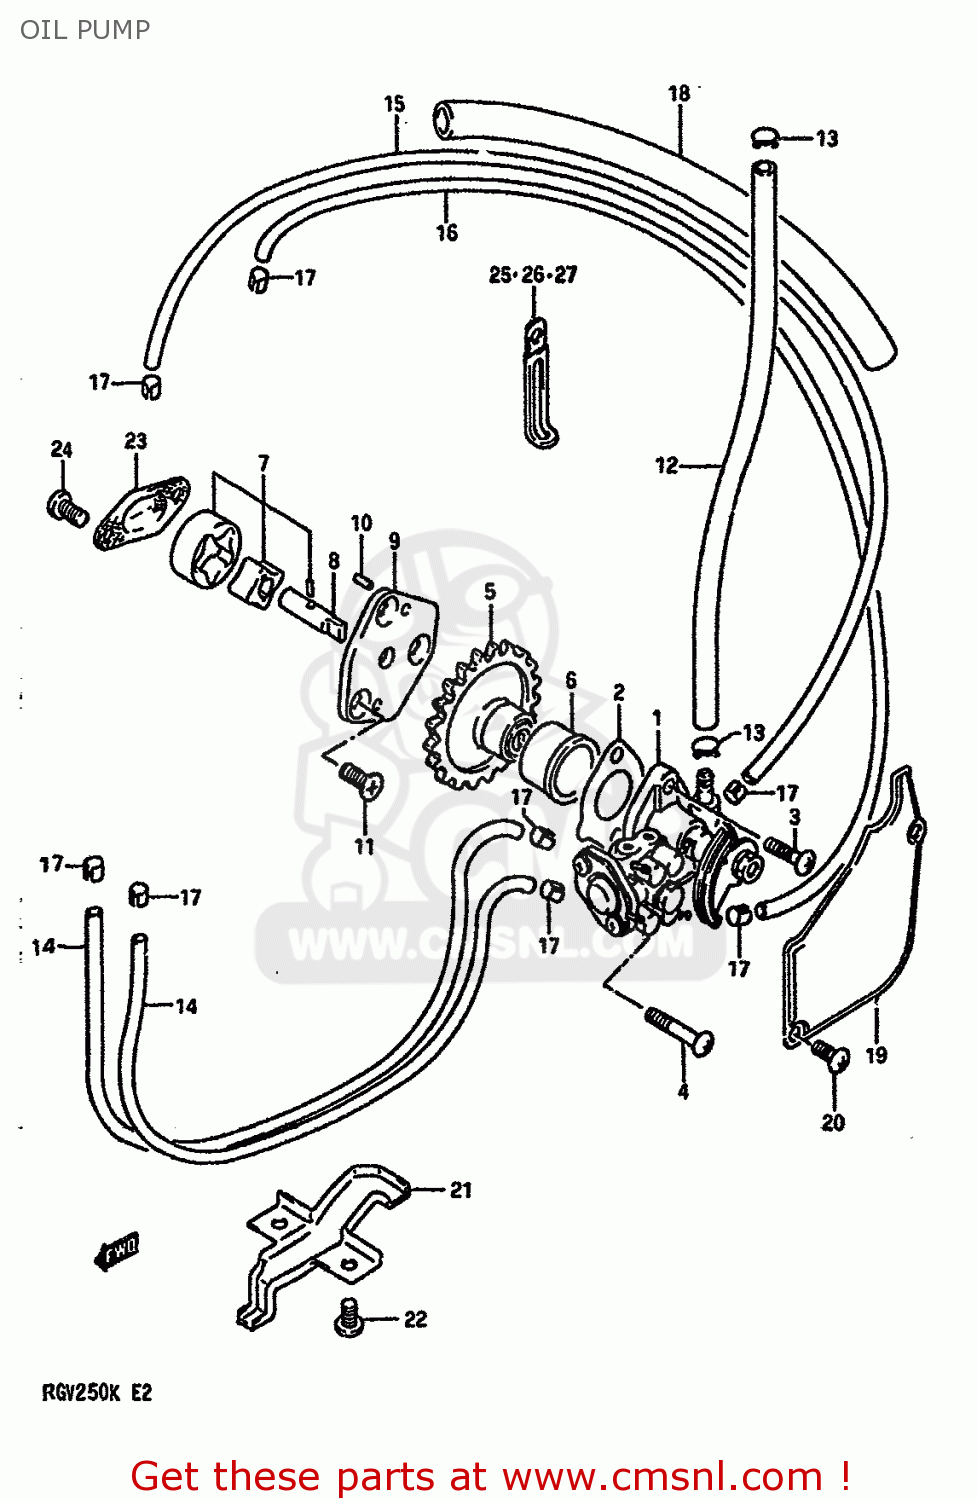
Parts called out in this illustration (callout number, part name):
1	PUMP ASSY,OIL
2	GASKET,OIL PUMP (NAS)
3	SCREW
4	SCREW
5	GEAR,OIL PUMP DRIVE(NT:21)
6	BUSH
7	ROTOR SET,OIL PUMP
8	SHAFT,OIL PUMP ROTOR DRIVE
9	COVER,OIL PUMP
10	PIN 4X6
11	SCREW
12	HOSE (4.5X8.5X600)
13	CLIP
14	HOSE (2X5X370)
15	HOSE (2X5X740)
16	HOSE (2X5X740)
17	CLIP
18	HOSE (11X15X500)
19	CAP,OIL INSPECTION
20	SCREW
21	COVER OIL HOSE
22	SCREW 6X12
23	STRAINER,ENGINE OIL
24	SCREW
25	CLAMP
26	CLAMP
27	CLAMP
